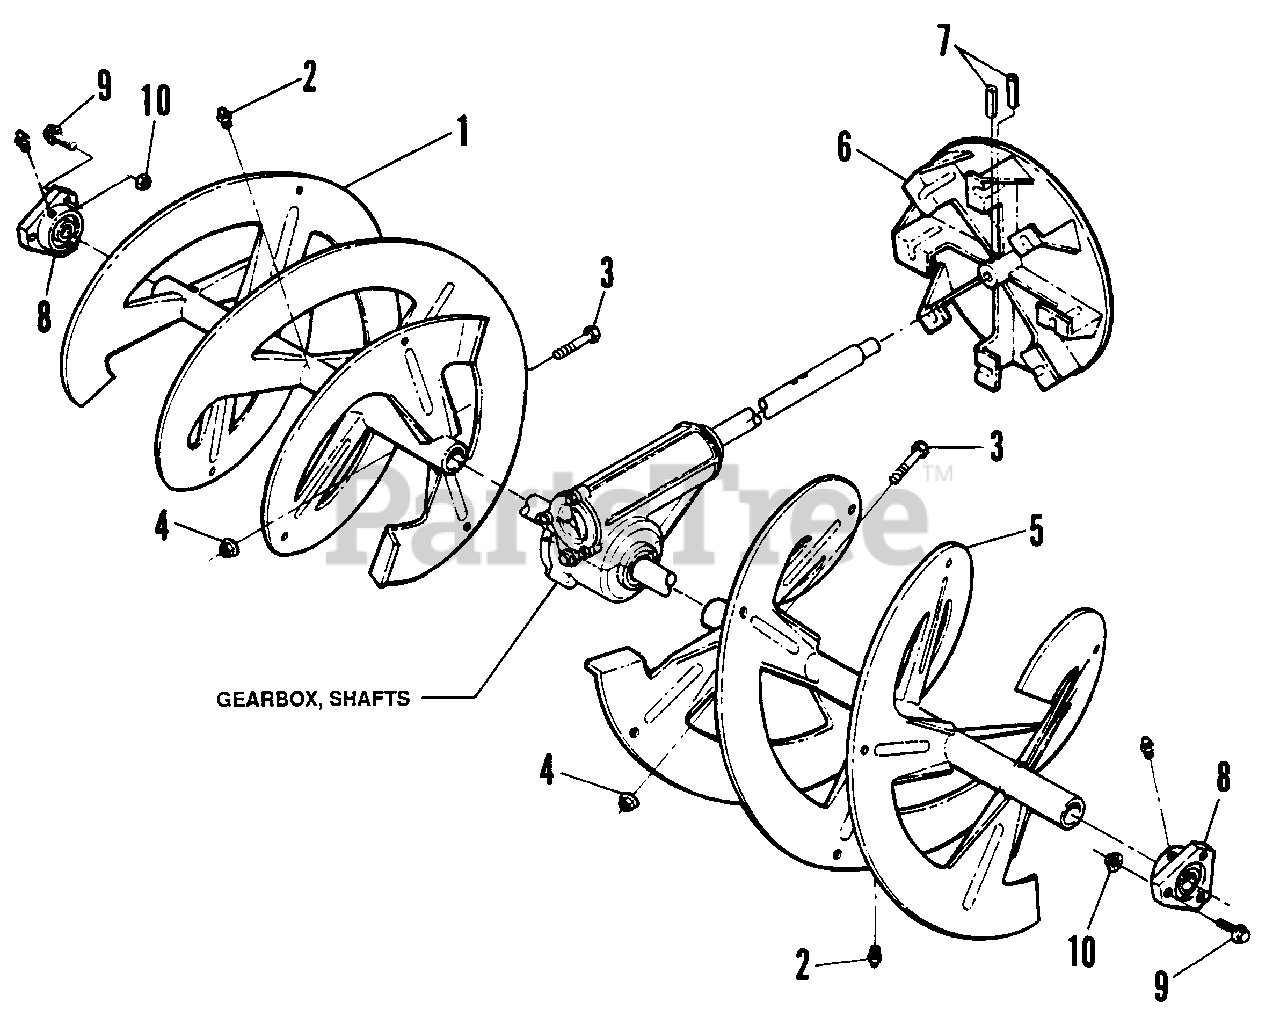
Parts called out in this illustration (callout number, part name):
1	AUGER, Right Side
2	LUBE FITTING, Straight (press-fit for .187 dia. Hole)
3	BOLT, 5/16-18 x 1-7/8" Shear
4	LOCKNUT, 5/16 - 18 Hex Flange
5	AUGER, Left Side
6	FAN, Impeller
7	PIN, Drive Lock
8	BEARING, Auger Shaft
9	BOLT, 1/4 - 20 x 3/4 Hex Flange Lock
10	NUT, 1/4 - 20 Hex Flange
